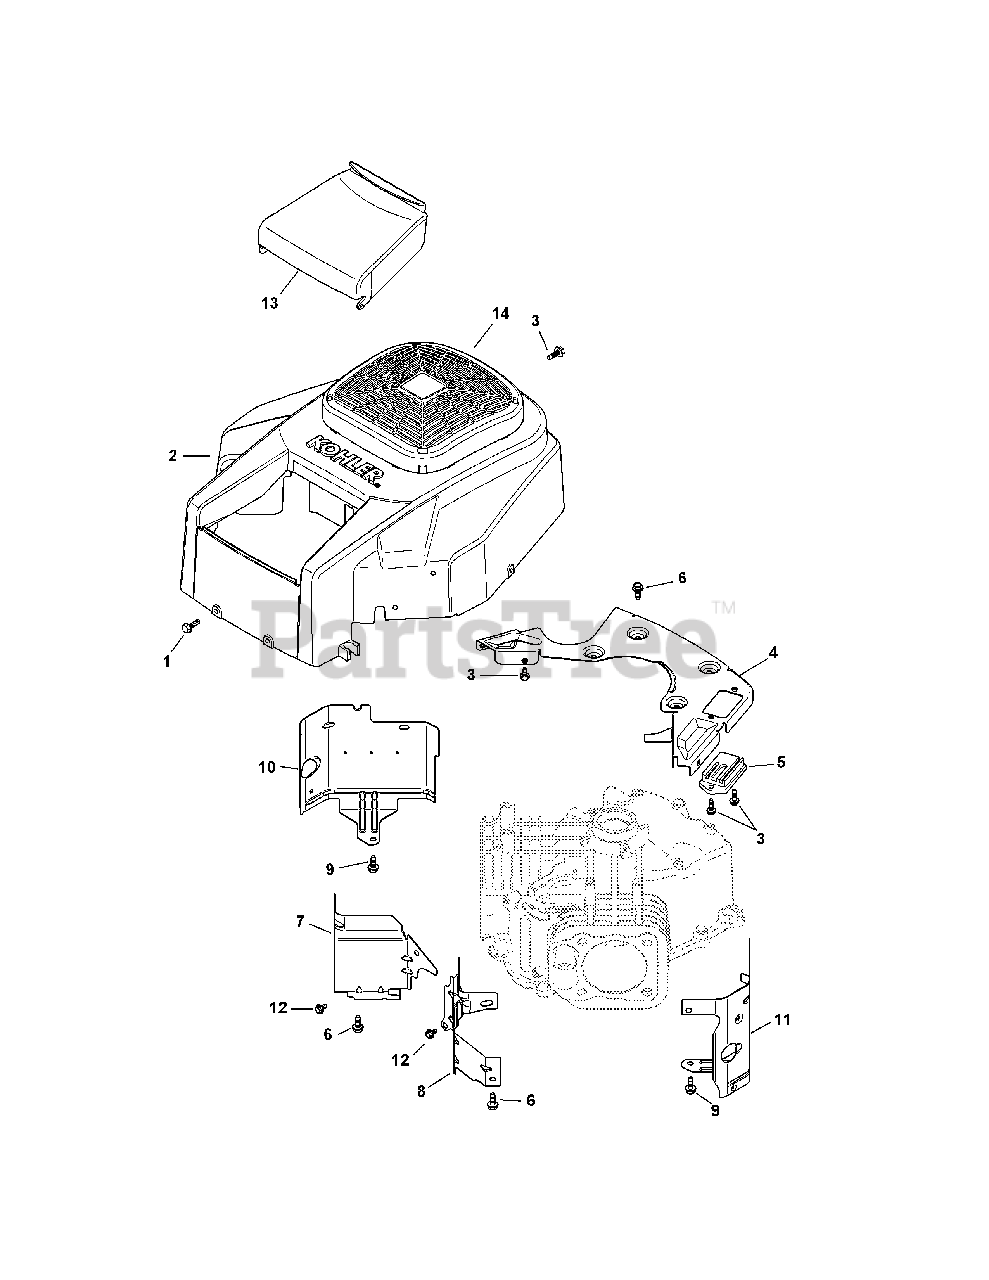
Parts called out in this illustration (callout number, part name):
1	Screw, M6 x 1.7 x 18
2	Blower Housing Kit
3	Flange Screw, M5 x .8 x 16
4	Backing Plate Kit
5	Regulator/Rectifier
6	Flange Screw, M6 x 1.0 x 16
7	Valley Baffle, #1 Cylinder
8	Valley Baffle, #2 Cylinder
9	Flange Screw, M6 x 1.0 x 10
10	Cylinder Barrel Baffle, #1 Side
11	Cylinder Barrel Baffle, #2 Side
12	Flange Screw, M5 x .8 x 10
13	Air Cleaner Cover
